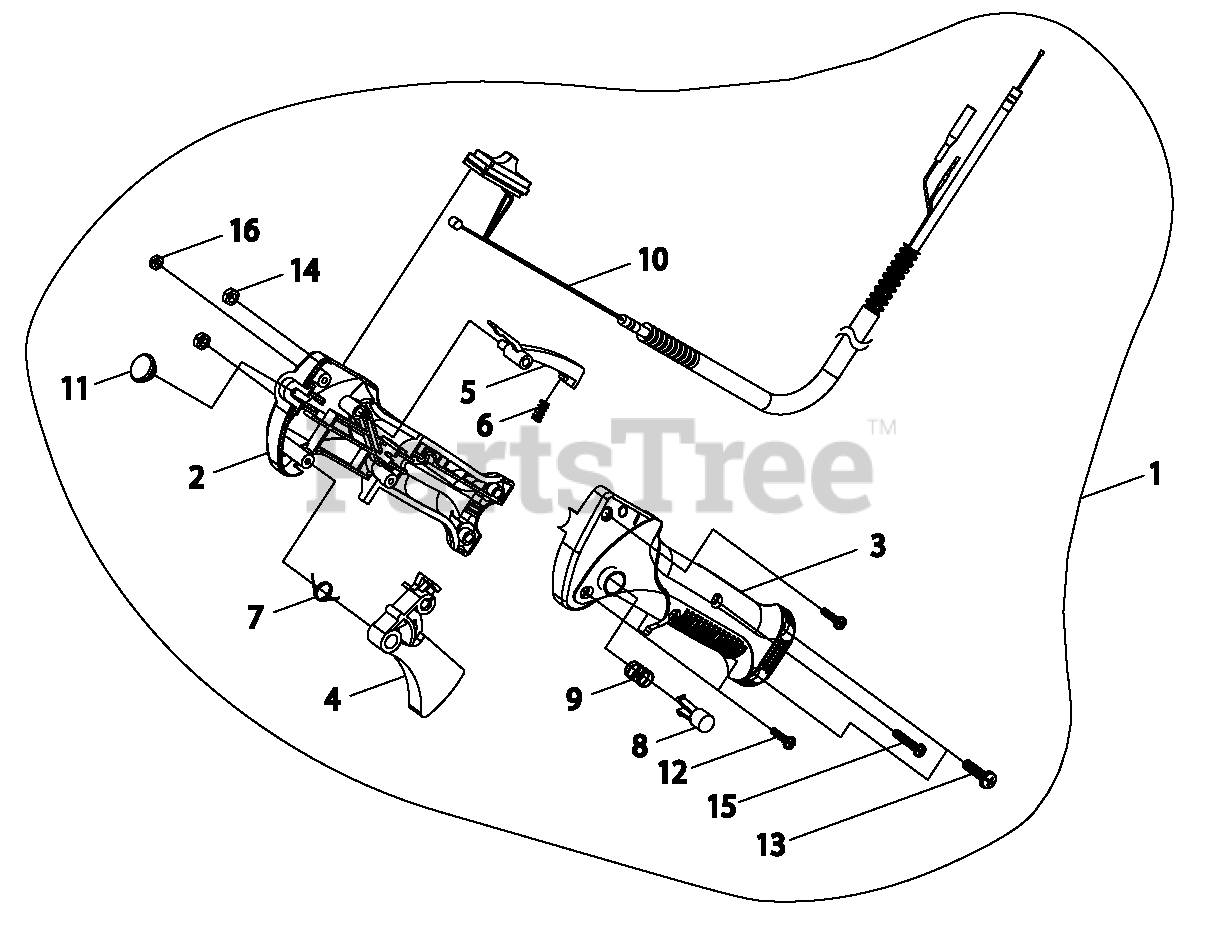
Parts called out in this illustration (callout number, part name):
1	THROTTLE CONTROL ASSY
2	CONTROL HANDLE - RIGHT
3	CONTROL HANDLE - LEFT
4	TRIGGER, THROTTLE
5	LOCKOUT, THROTTLE
6	SPRING, COMPRESSION
7	SPRING, TORSION
8	BUTTON, THROTTLE LOCK
9	SPRING, COMPRESSION
10	CABLE ASSY, CONTROL
11	PLUG, RUBBER
12	SCREW, TAPPING 4×16
13	SCREW M5×20
14	NUT M5
15	SCREW M4×23
16	NUT M4
